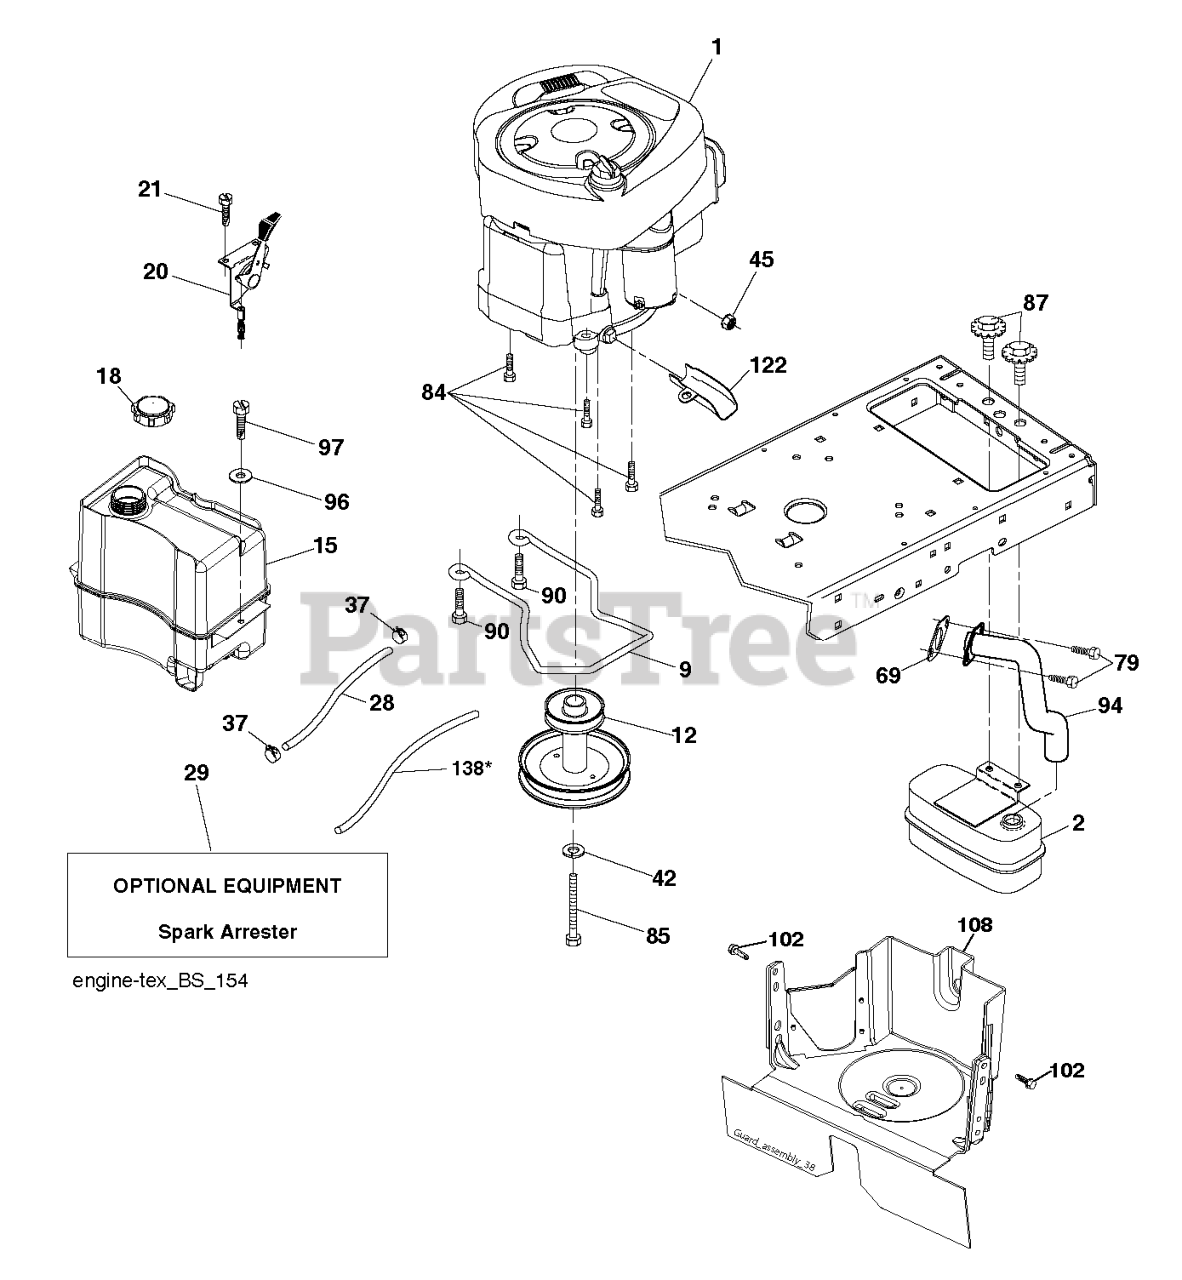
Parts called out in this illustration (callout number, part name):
2	MUFFLER.SINGLE.CYL.KOHL/B&S
9	KEEPER.BELT.ENG.4.25"2.BLT.431
12	ENGINE.PULLEY
15	Tanks
15	FUEL.TANK.ASM.NON-EPA
18	CAP ASM.FUEL.2.25"FR.
20	THROTTLE.COBRA.21".RSTART.BLK
28	LINE.FUEL.20
29	KIT.SPARK ARRESTOR 794945 B&S
37	HOSE CLAMP
69	REPL BY 532 27 22-93
84	SCREW.3/8-16
85	BOLT.HEX.7/16-20X4.GR5.1.5BLUE
87	BOLT.5/16-18UNCX3/4 W/SEMS.BLK
90	SCREW 3/8-16X1
94	EXHAUST.TUBE.B&S.28/31
97	SCREW HEXWSHR 1/4-20X3/4
108	COVER ENGINE PULLEY COVER WITH
122	EXTENSION DRAIN OIL
